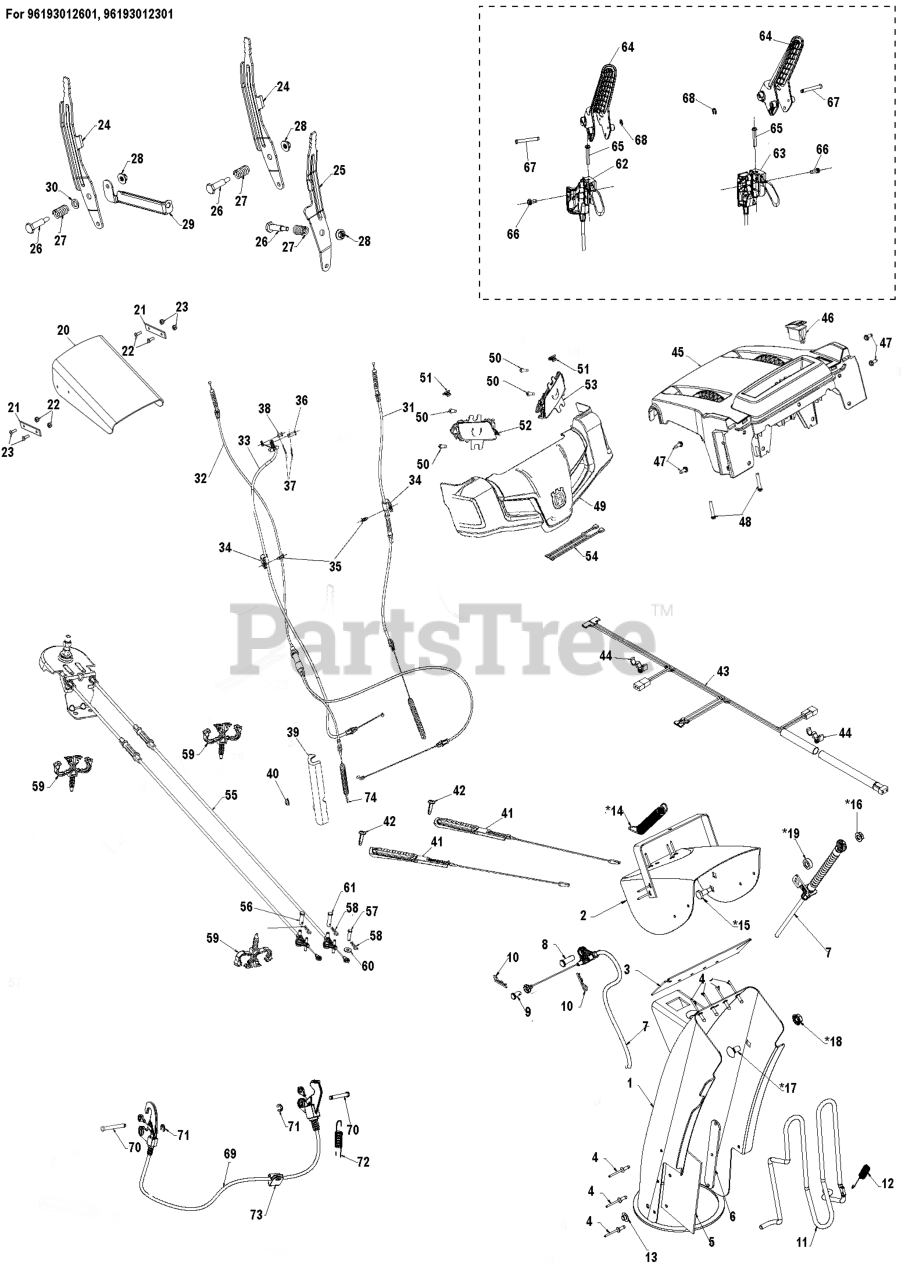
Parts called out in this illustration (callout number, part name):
1	ASM.CHUTE/DEFLECTOR.668
7	CABLE CONTROL.CHUTE.DEFLECTOR.
8	PIN CLEVIS 5/16X.875
9	PIN CLEVIS .25 X .31
10	HAIRPIN.SOFT.ZINC.059X1.125
11	GUARD ROD CHUTE GUARD SHORT CL
12	SPRING.CHUTE.GUARD
13	NUT
20	SHIELD.DEFLECTOR.BLACK.SNOW
21	STRAP.DEFLECTOR.SHIELD
22	SCREW.MACHINE.8-32 X 1/2-BLK
23	NUT.HEX.NYLOCK
24	LEVER.CONTROL.SPEED/DEFLEC.BLK
25	LEVER.CONTROL.CHUTE.ROTATON.BL
26	BOLT SHOULDER_HEX HD_1/4-20_3/
27	SPRING.COMPRESSION.82LBS
28	NUT HEX_LRG FLG_1_4-20_LOCK
29	BRACE.SUPPORT.SPEED.BLACK
30	WASHER.FLAT.625 X .375 NYLON
31	Cables
31	CABLE DRIVE WITH ADJUSTER
32	CABLE IMPELLER
33	CABLE.CONTROL.SPEED.DSST.OPP
34	CLIP.CABLE.BLK
35	FASTENER.PUSH.O.250X0.783
36	PIN CLEVIS 5/16X.875
37	HAIRPIN.SOFT.ZINC.059X1.125
38	PIN CLEVIS .25 X .31
39	COVER AUGER CABLE
40	NUT HEXAGON FLANGE 5/16-18 ST
41	GRIP.HANDLE.HEATED
42	SCREW.PAN.HD.TORX.1/4-20X.750
43	Harnesses
43	HARNESS WIRE.LIGHT AND GRIPS
45	CONSOLE.BASE.MULTICONT.498SWIT
46	SWITCH HEATED GRIP BLK
47	SCREW 14-20 X 5/8
48	SCREW HEX_WASH_13-16 X 1.50_H
49	COVER CONSOLE_ASM_HUSQVARNA
50	SCREW.HWH.13-16-5.8.BZP
51	CLIP PANEL ERGO 30603
52	LIGHT ASM.HUSQVARNA.RH
53	LIGHT ASM.HUSQVARNA.LH
54	HARNESS.WIRE.LIGHT.JUMPER
55	CABLE ASSY CONTROL
56	PIN CLEVIS 5/16X.875
57	PIN.CLEVIS
58	HAIRPIN.SOFT.ZINC.059X1.125
59	CLIP.CONDUIT.DOUBLE LOOP
60	WASHER FLAT_.250 X .625 X .06
61	PIN CLEVIS CLEVIS
62	CABLE.POWER STEERING.LHS
63	CABLE.POWER STEERING.RHS
64	LEVER ENGAGMENT
65	SCREW HEX_WASH_13-16 X 1.50_H
66	SCREW 14-20 X 5/8
67	PIN.GROOVED
69	CABLE INTERLOCK CONTROL ACETAL
70	PIN.GROOVED
72	SPRING RETURN_INTERLOCK_DSST
73	CLIP.CABLE.BLK
74	SPRING EXTENSION; AUGER EXTENS
